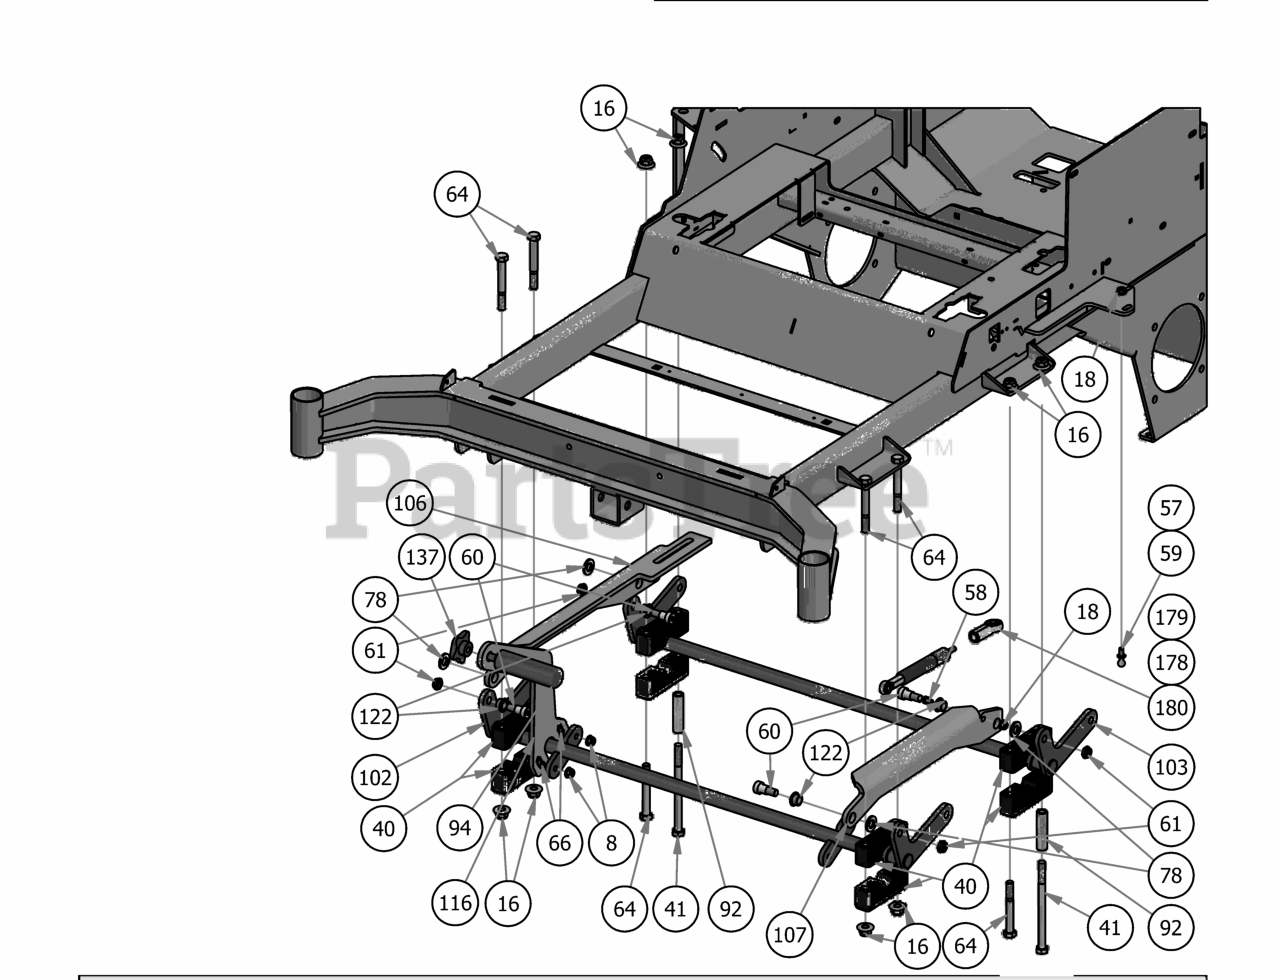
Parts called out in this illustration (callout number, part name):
8	3/8" Nylock Flange Nut
9	1/2" Flange Nut
12	1/2" Hex Nut
16	1/2-13 Nylon Flange Nut
17	1/4-20 Hex Flange Nuts Zinc w/Serrations
18	5/16" Flange Nut
40	Pillow Block Assembly
41	1/2 x 7 Hex Bolt Grade 5
45	1/2 x 2-1/2 Carriage Bolt
57	13mm Damper Ball Stud-Steering
58	10mm Damper Ball Stud-Steering
59	10mm Damper Ball Stud-XP Linkage
60	5/8'' x 5/8'' Shoulder Bolt
61	1/2" Nylcock Nut (1/2 Jam)
62	1/4-20 x 1-1/4 GR 5 Hex Bolt
64	1/2" x 4" Bolt (Grade 8)
66	3/8" x 1 1/4" Carriage Bolt
75	.517 Square Hole Round Washer
78	.630 ID Plastic Washer
84	.505 Nylon Spacer
88	5/8" Split Collar
90	MZ Deck Idler Spacer
92	2019 Deck Stop Spacer
94	Knurled Pedal
100	Dial Rod Plunger
101	2019 Outlaw Gen2 Deck Height Dial Rod Assy
102	2019 Outlaw Actuator - Front
103	2019 Outlaw Actuator - Rear
106	2019 Actuator Linkage - Right
107	2019 Actuator Linkage - Left
116	Foot Lift Upright Lever
117	2019 Outlaw Deck Travel Lock
122	Bronze Bushing - SF - 2024-8
124	Brake Spring
136	Seat Braket Pin
137	Foot Pedal Knob 1/2-13
162	Travel Lock Rubber Grip
165	2019 Rigid Frame
178	200 lb Gas Spring- 54" Deck outlaw
179	250lb Gas Spring - 61" Deck
180	300lb Gas Spring - 72" Deck
